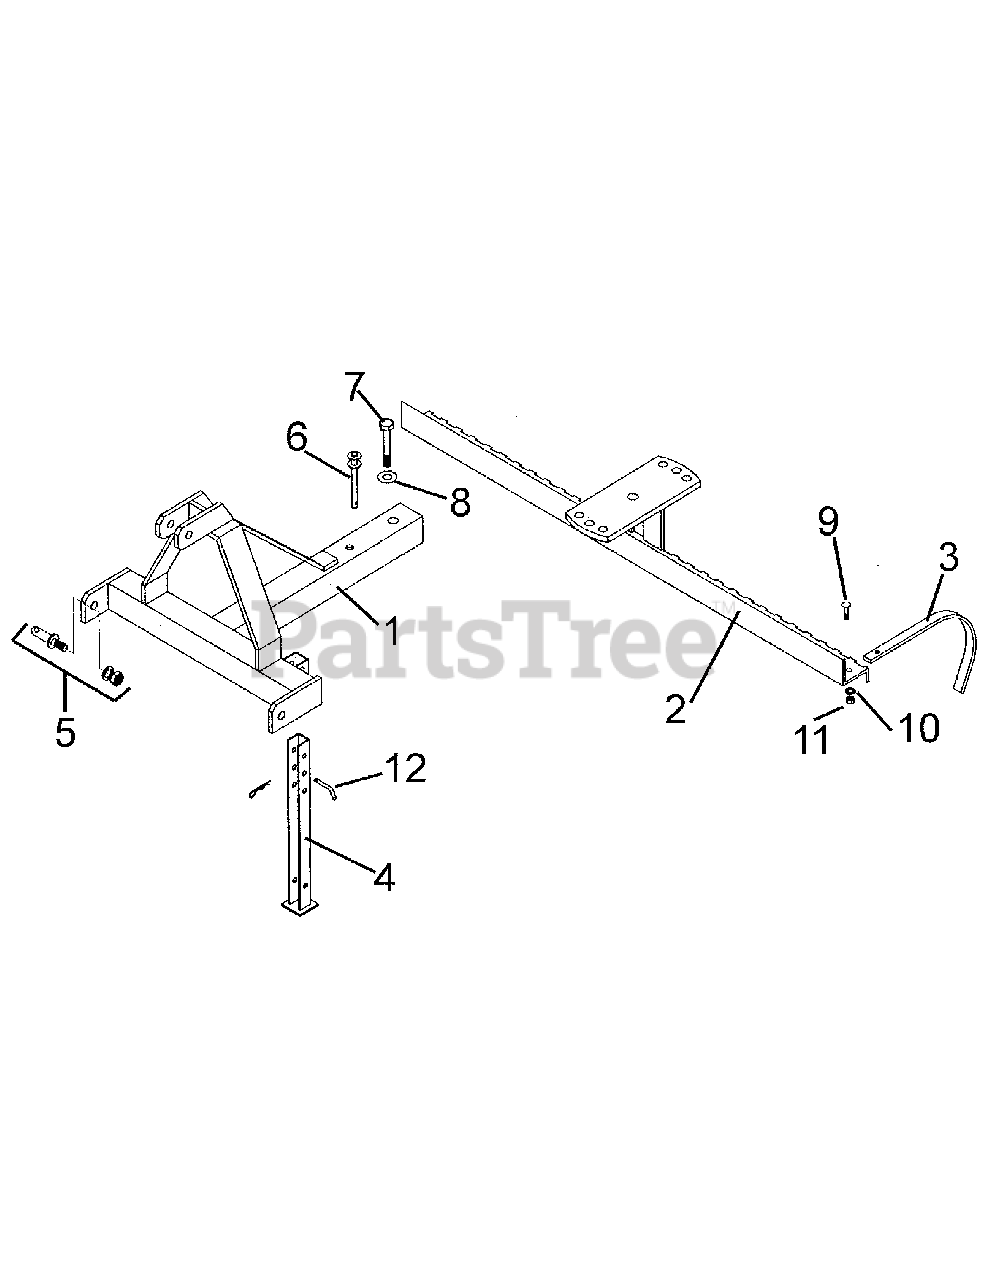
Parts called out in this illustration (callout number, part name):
2	WELDED SWIVEL 5'
4	FOOT STAND
5	7/8" HITCH PIN W/LW & NUT
6	SWIVEL PIN W/COTTER
7	3/4" X 5" HEX BOLT PLATED
8	3/4" ID FLAT WASHER
9	3/8"-16 X 1" CARRIAGE BOLT
10	3/8" LOCKWASHER
11	3/8" HEX NUT
12	LOCK PIN
